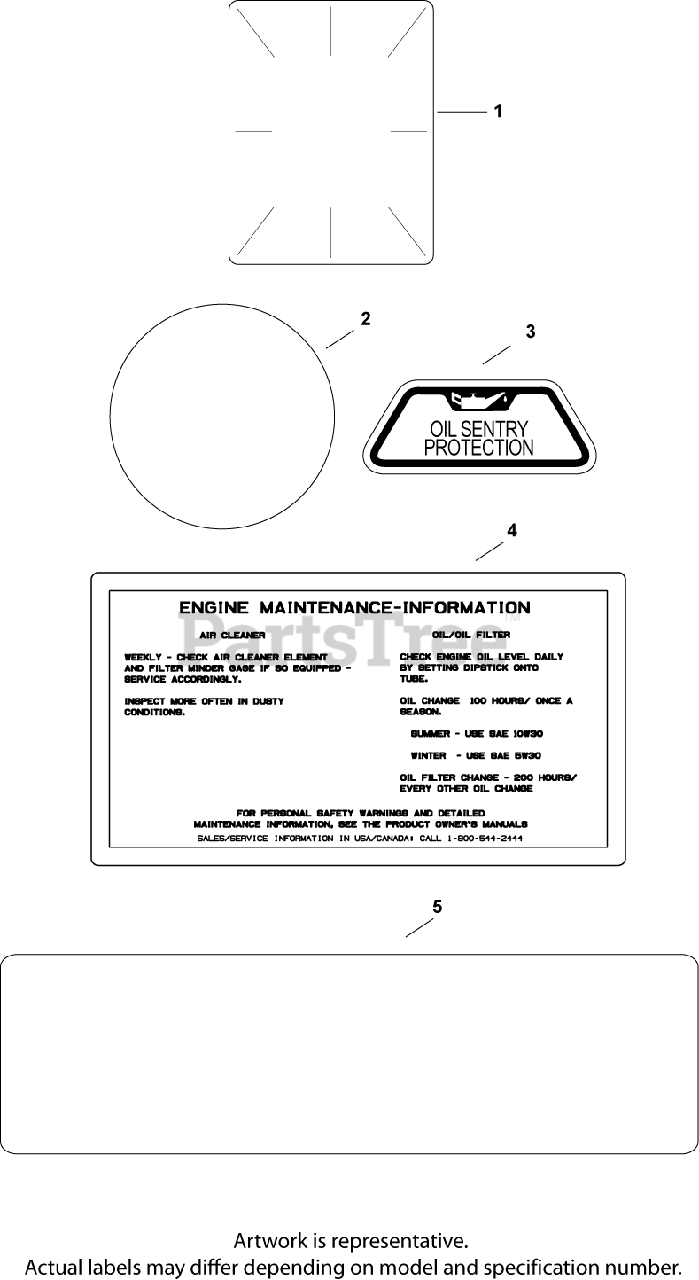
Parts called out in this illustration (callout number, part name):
1	DECAL, CLEAR LAMINATE USE 25 113 70-S
2	LABEL, (ROUND KOHLER GOLD)-USE 24 113 18
3	DECAL, OIL SENTRY - (#DSC)
4	DECAL, AIR CLEANER - (#DSC)
5	DECAL, 27 HP
